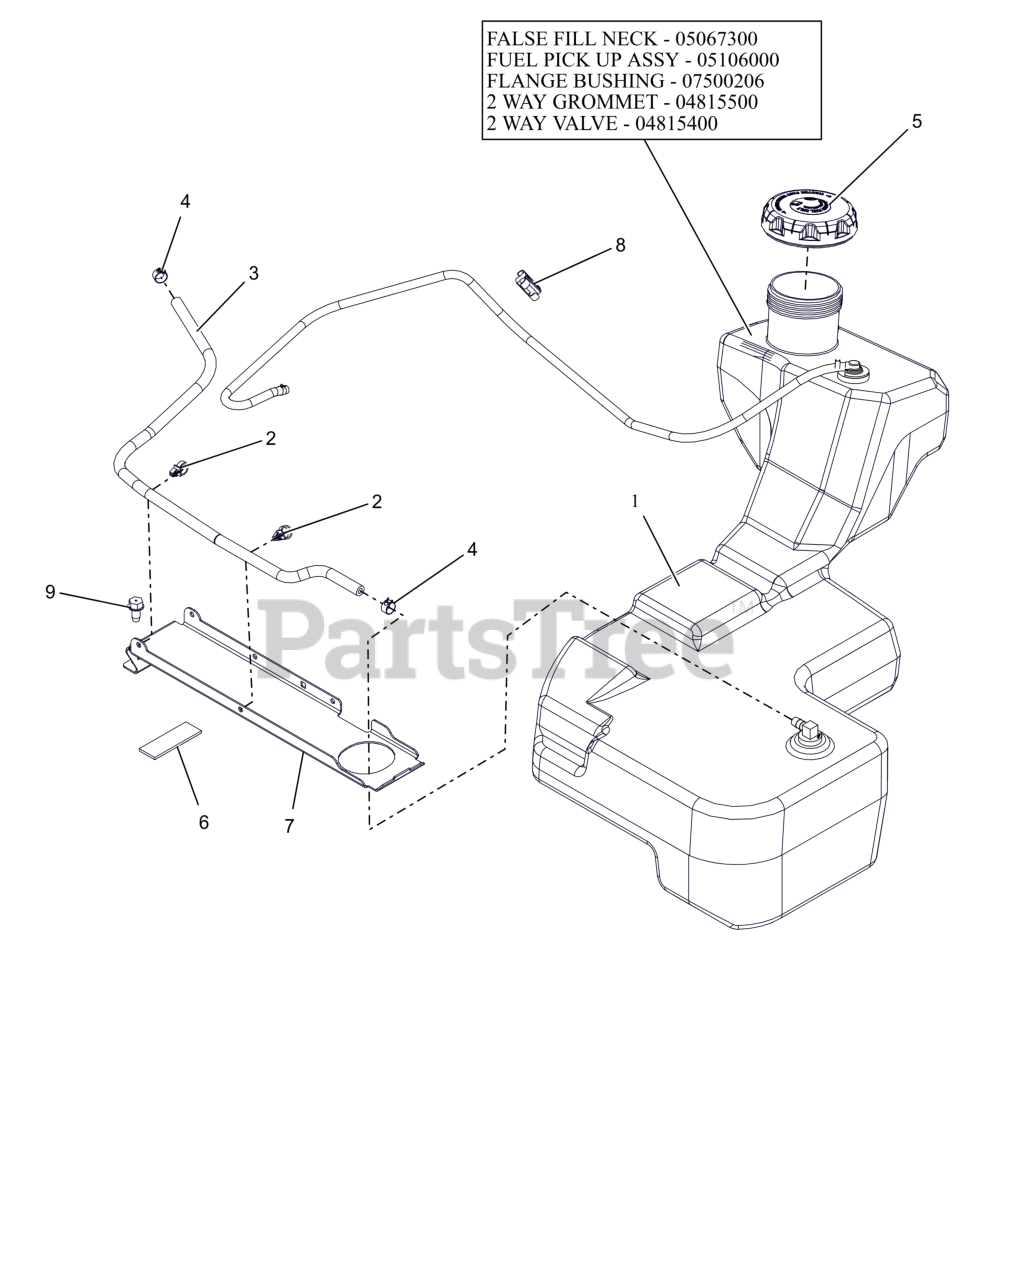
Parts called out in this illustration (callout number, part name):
1	ASM, FUEL TANK-HD
1	INSERT, FUEL NECK FALSE FILL
1	ASM, HD FUEL PICK-UP
1	BSHG-FLG .375X1.062X.625 NITR
1	GROMMET, 2-WAY
1	VALVE, 2-WAY
2	ROUTING CLIP (1/2" ID)
3	HOSE, .25 LOW-PERM BULK GAS
4	CLAMP, FUEL LINE
5	CAP, FUEL VENTIN AUTOLOCK
6	PAD,RBR 1.0"X3.0" W/ADHESIVE
7	BRKT, FUEL TANK HOLD DOWN
8	CLIP, T, .38-.50
9	SCR,TAP .375-16X.75 HWH TR ZCC
